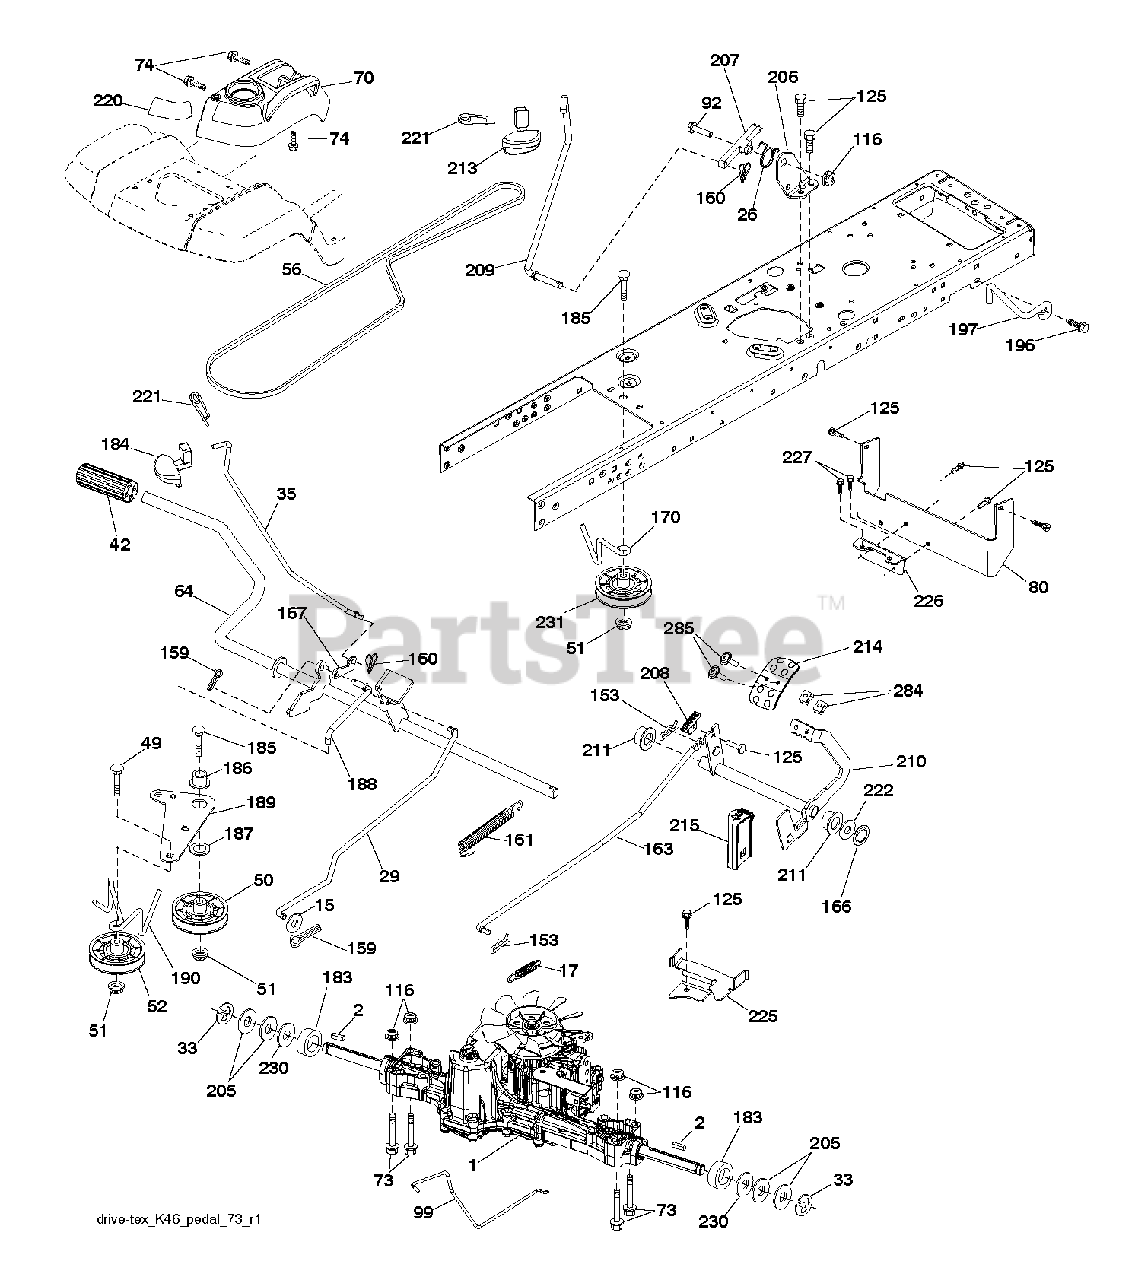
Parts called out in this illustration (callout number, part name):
2	SQUARE KEY
15	WASHER
17	SPRING.BRAKE.K46.GREEN
26	SPRING.RETURN.CRUISE
29	ROD.BRAKE.K46
35	ROD.BRAKE.PARTK.HUSQ.TEX
42	PEDAL COVER T
50	IDLER.FLAT.910.OFFSET
51	NUT LOCK FLG 3/8-16 UNC
52	IDLER.V-GROOVE.910.OFFSET
56	V-BELT.MOWER.92.40.42/K46
64	SHAFT.ASM.PEDAL.BRK.CNTR
70	CONSOLE.ASM.RH.GT.FC.HUSQ
73	BOLT HEX 5/16-18 GR 5
74	SCREW.HI-LO.CONSOLE
80	STRAP.TORQUE.K46.K57R.TT
92	BOLT
99	ROD.SPRING.BYPASS.K46.LT.Z
116	NUT LOCK HEX FLANGE 5/16-18
125	SCREW
153	RETAINER M
159	COTTER PIN
160	RETAINER CLIP
161	SPRING, RETURN LT
163	ROD.CONTROL.PEDAL.K46
166	NUT.PUSH.625
167	LATCH.BRAKE.SPRING
170	KEEPER.CENTER SPAN.1.688
183	SPACER AXLE
184	RB HANDLE.PARKG.BRK.HUS/PRED
186	SPACER.RETAINER
187	WASHER 12/32X2X10GA
188	RP LINK.CLUTCH.GROUND.DRIVE
189	BELLCRANK.GROUND.DRIVE.TEX.
190	KEEPER.BELLCRANK.DRIVE
196	SCREW 3/8-16X1
197	LINK.CLUTCH.ANIT-ROTAT
206	BRKT.MOUNT.LATCH.CRUIS
207	LATCH.CONTROL.CRUISE
208	GEAR.SECTOR.CONTROL.CR
209	ROD.CONTROL.CRUISE.GT.
210	ROCKER.ASM.PEDAL.CONTR
211	BEARING.NYLON
213	KNOB.CONTROL.CRUSIE.HU
214	PEDAL.FORWARD.HUSQVARNA.DEALER
215	PEDAL.REVERSE.TEX.GT.4
220	REFLECTOR.RH.TEX GT
221	RETAINER.SPRING.CLIP.H
222	WASHER 21/32 X 1-1/4 X 10 GA.
225	KEEPER.BELT.TRANSAXLE.K46
226	BRACKET.MOUNT.TORQUE.K46.TLT
227	SCREW
230	WASHER.HARDENED
231	IDLER.V-GROOVE.1.688.OFFSET
284	NUT.U-CHNL.1/4-20.550DP.350PNL
285	SCREW.MACHINE.CR.1/4-20
